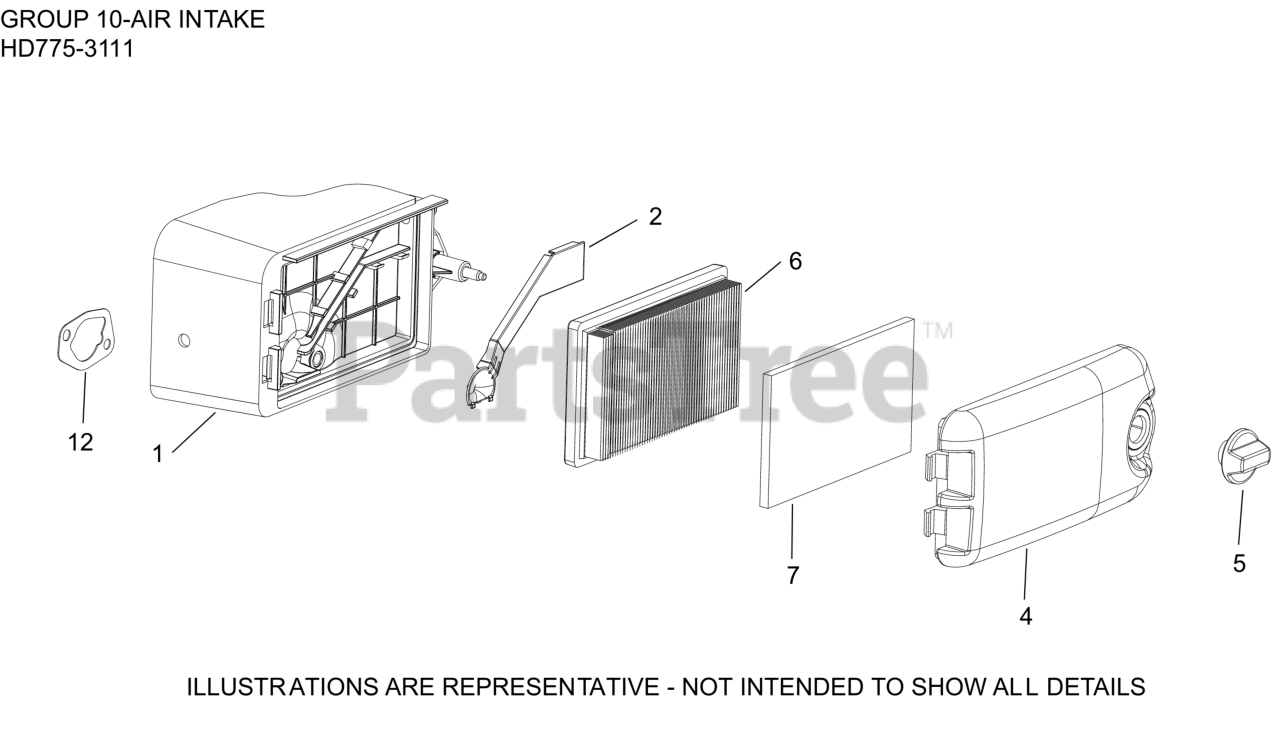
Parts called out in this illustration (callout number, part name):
1	KIT, AIR CLEANER BASE
2	COVER, A/C BASE (BREATHER GAS)
4	COVER, AIR CLEANER
5	KNOB-USE 14 341 07-S
6	ELEMENT, AIR FILTER
7	ELEMENT, PRE-CLEANER
12	GASKET, AIR CLEANER BASE
